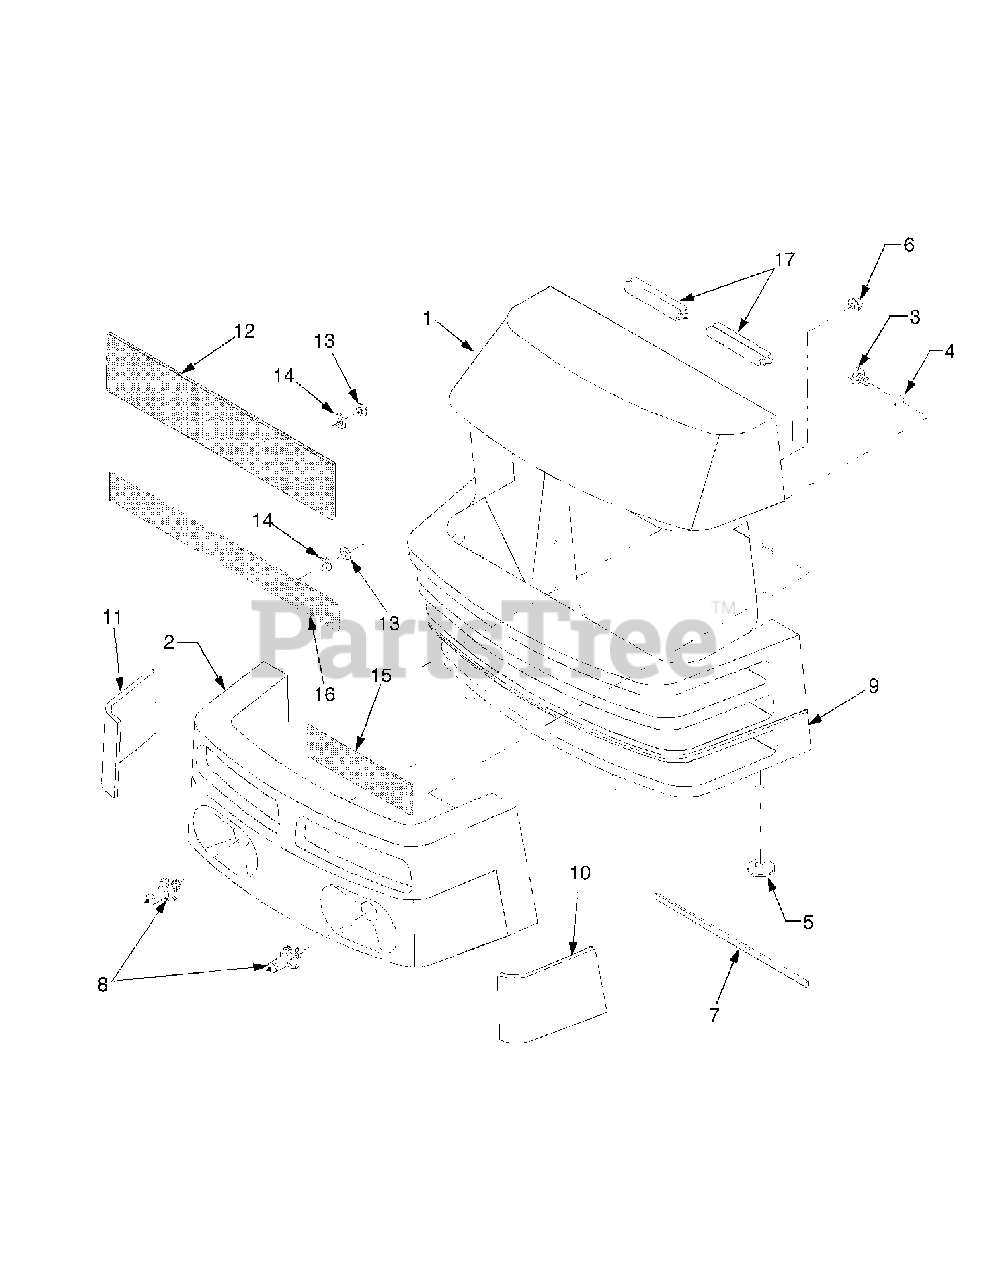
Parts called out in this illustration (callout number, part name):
1	Front Grill Ass'y
2	Head Lamp Ass'y
4	Washer, Plain
5	Rubber, Cushion
7	Cushion, Front Grill
10	Cover, Head Light Side (LH)
11	Cover, Head Light Side (RH)
12	Screen, Front Grill (Upper)
15	Screen, Front Grill (Lower)
16	Screen, Front Grill (Lower)
